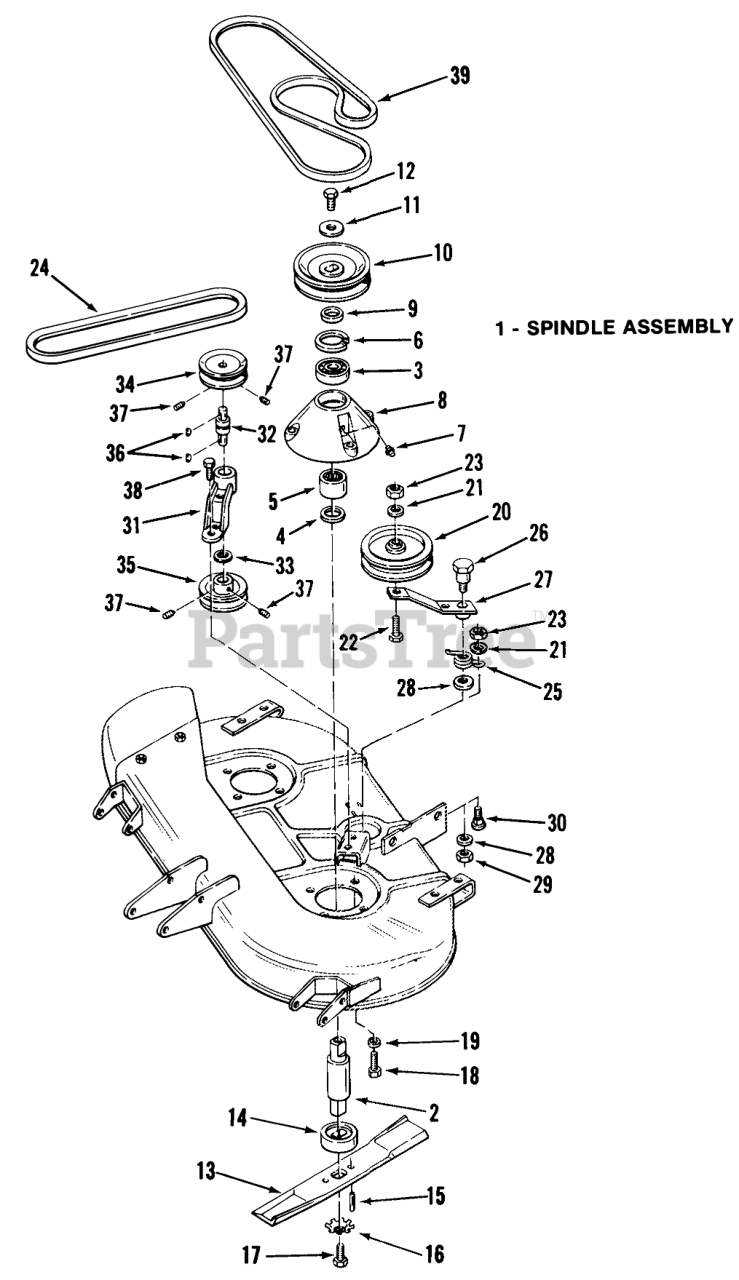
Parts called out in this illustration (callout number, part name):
1	Spindle Assembly (Includes Items 2 Thru 8)
2	SPINDLE MOWER
3	BEARING-BALL
4	OIL SEAL
5	BEARING-NEEDLE
6	INT SNAP RING
7	Fitting-Grease
8	HOUSING
9	SPACER
10	PULLEY-BLADE
11	WASHER
12	Bolt
13	S/A BLADE KIT
14	Spindle Cup
15	SPIROL ROLL PIN
16	WASHER
17	Bolt
18	Bolt
19	LOCKWASHER
20	Idler Pulley
21	Washer
22	BOLT
23	Nut
24	V-BELT
25	SPRING-TORSION
26	BOLT-SHOULDER
27	Idler Arm
28	WASHER
29	Hex Nut 7/16-14
30	Bolt
31	HOUSING DRIVE BRG R
32	BEARING-INT SHAFT
33	Snap Ring
34	PULLEY
35	PULLEY-SPLIT
36	KEY-WOODRUFF
37	Set Screw
38	Bolt
39	V-BELT
